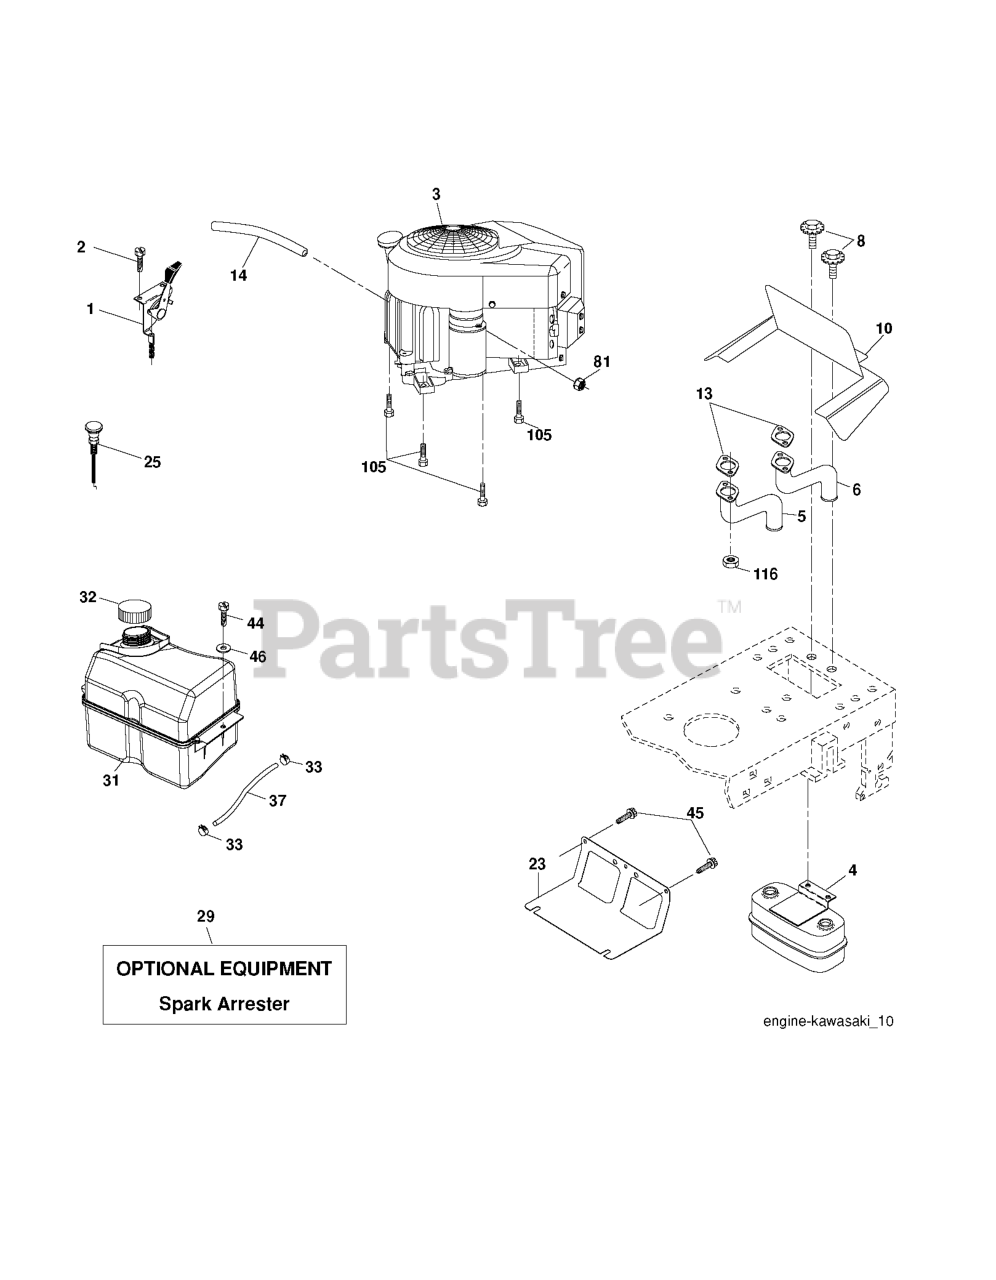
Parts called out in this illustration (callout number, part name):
1	THROTTLE CABLE
2	SCREW
4	MUFFLER.TWIN.CYL.LOW.TONE
5	EXHAUST TUBE LH KAWI
6	EXHAUST TUBE RH KAWI
8	BOLT.5/16-18UNCX3/4 W/SEMS.BLK
10	RP SHIELD HEAT MUFFLER
13	GASKET.EXHAUST.KAWASAKI.15-1
14	TUBE, DRAIN OIL ASM.
23	SHIELD.BROWNING.DBR.GUARD
25	CONTROL, CHOKE
29	KIT.SPARK ARRESTOR 794945 B&S
31	TANK.ASM.FUEL.FR.2.5GA.
32	FUEL CAP
33	HOSE CLAMP
37	LINE.FUEL.20
44	SCREW HEXWSHR 1/4-20X3/4
45	SCREW, 3/8-16X3/4
81	NUT
105	SCREW 3/8-16X1
116	NUT.HEX.FLANGE.TOPLOCK
